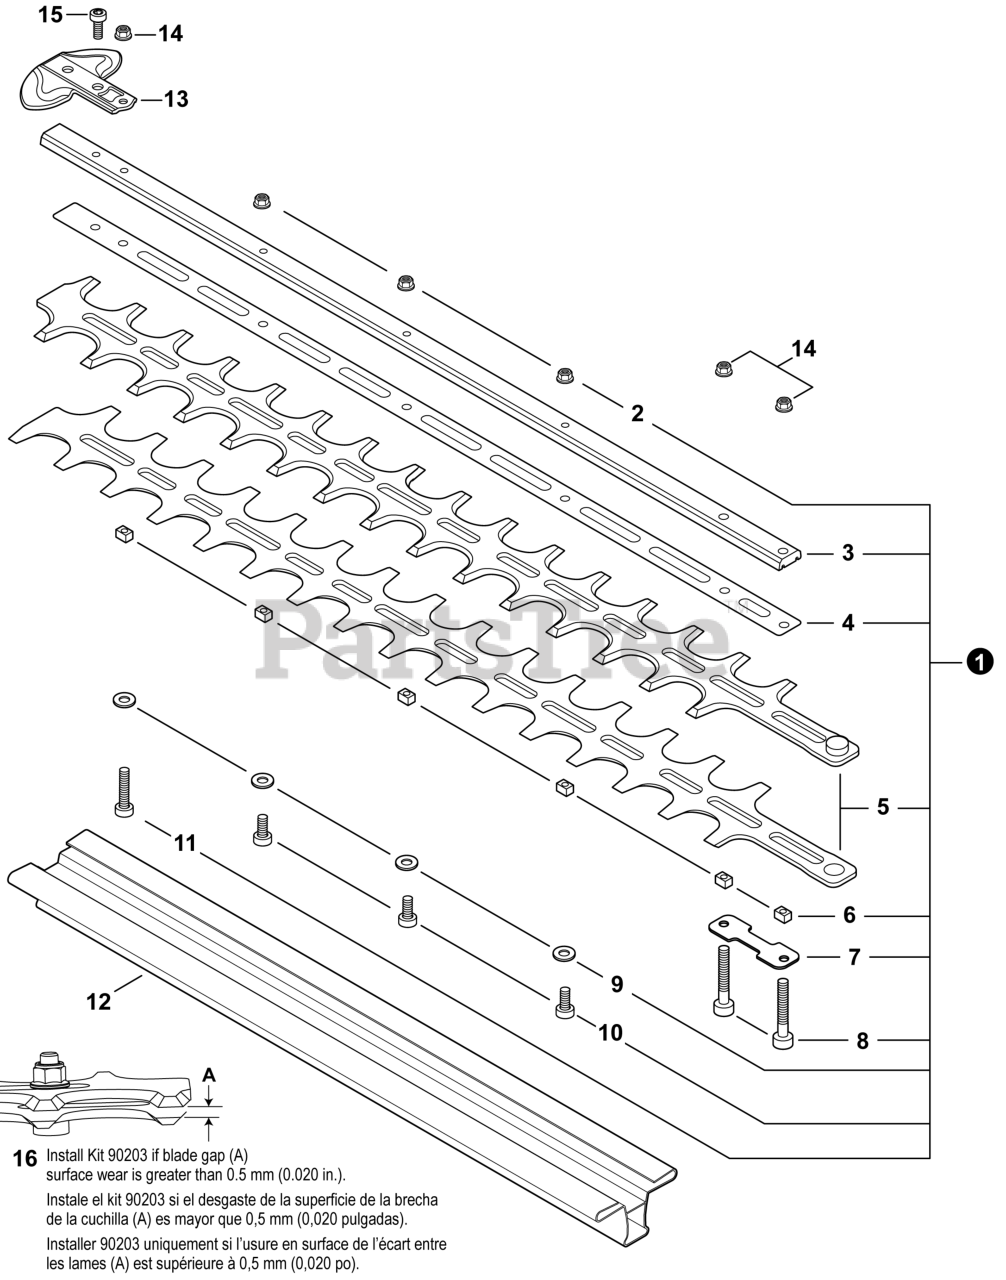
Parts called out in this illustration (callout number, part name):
1	CUTTER ASSY, 20"
2	NUT, FLANGE M5
3	SUPPORT, CUTTER 20"
4	PLATE, CUTTER 20"
5	CUTTER, 20"
6	GUIDE, BLADE 5
7	PLATE, EYE
8	BOLT, TORX 5x30
10	BOLT, TORX 5x20
11	BOLT, TORX 5x25
12	SCABBARD - BLACK
13	GUARD, TIP
14	NUT, FLANGE M5
15	BOLT, TORX 5x8
16	BLADE KIT, ADJUSTABLE
